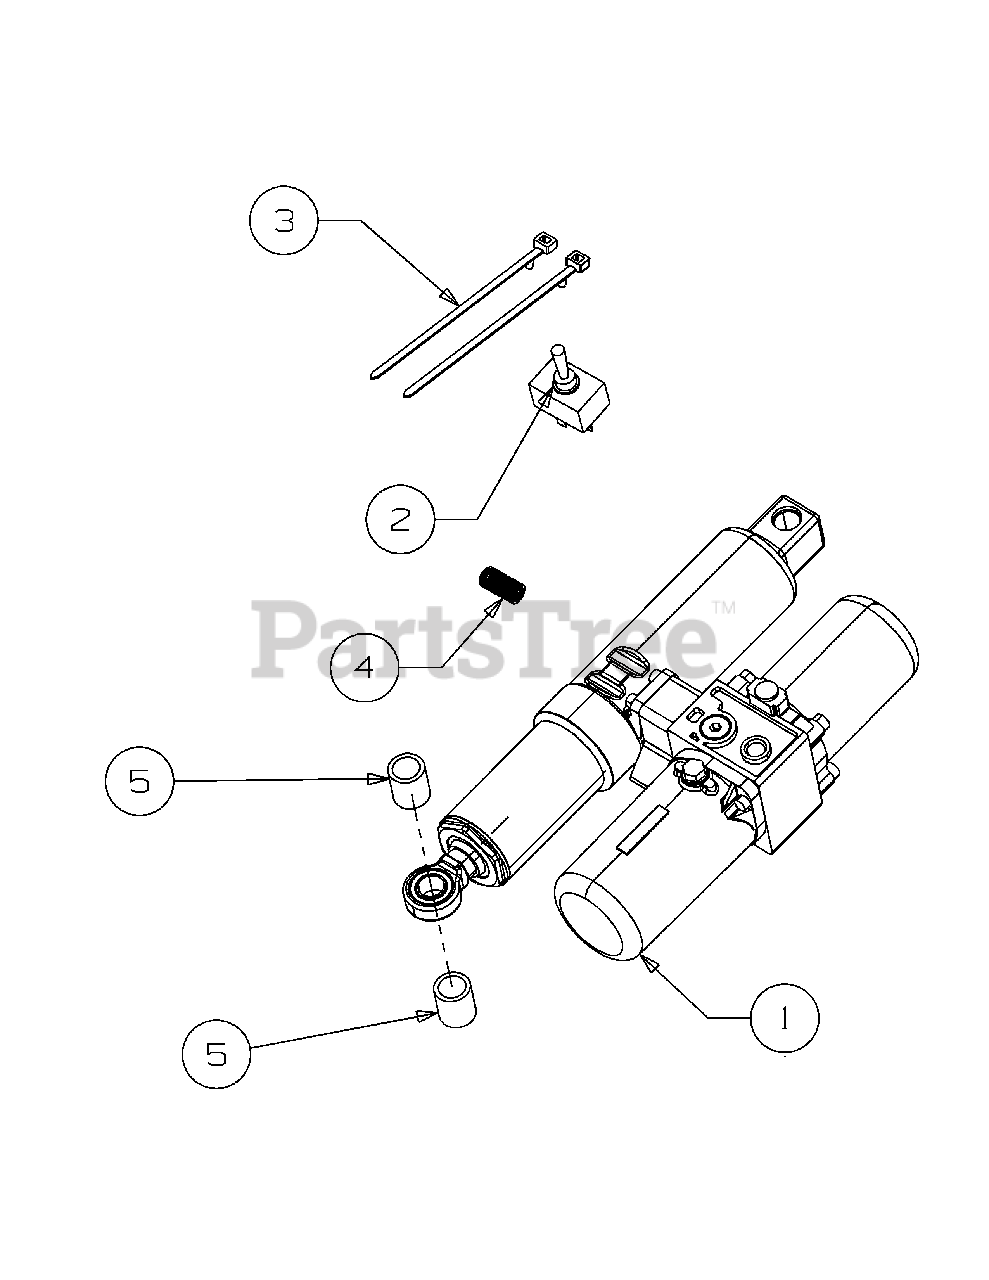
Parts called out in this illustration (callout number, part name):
1	Angle Actuator Complete
2	On-Off-On Toggle Switch
3	Cable Tie
5	Spacers, .88ODx.69IDx1.00LG
